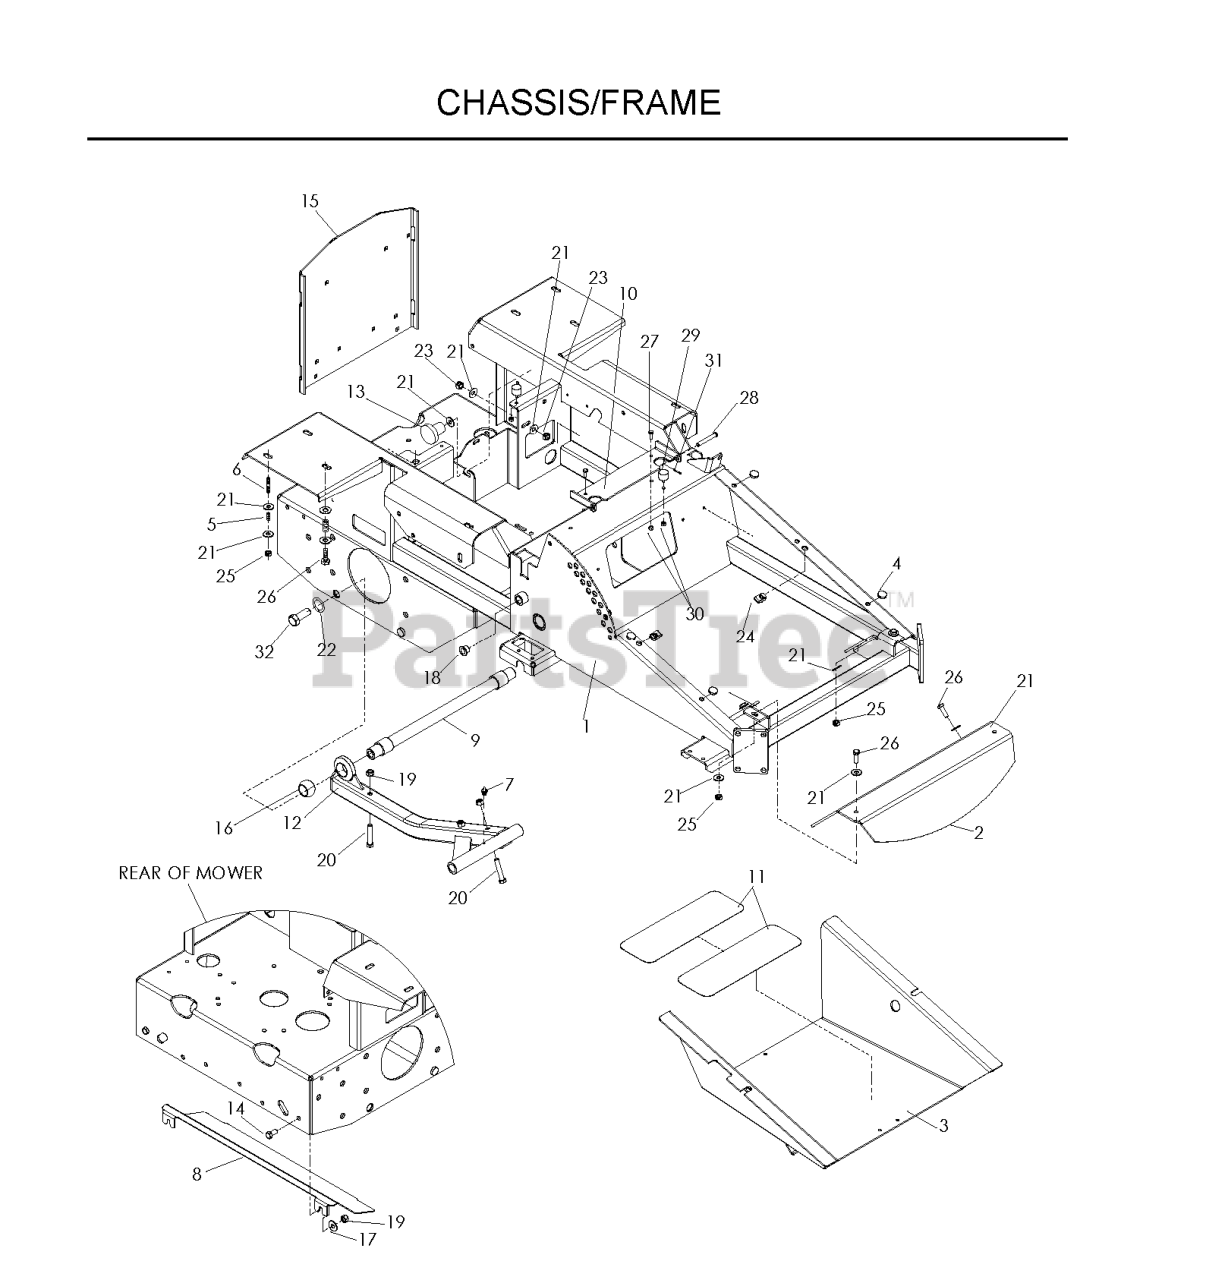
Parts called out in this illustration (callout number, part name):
1	CHASSIS W/DECALS
2	FOOTREST ORANGE
3	IZ FOOTPLATE W/DECAL
4	GROMMET, BUMPER
6	STUD, 5/16C
7	ZERK
8	REAR GUARD
9	STRUT MOUNT WELDMENT
10	SEAT BRKT W/DECAL
11	ANTI-SKID PAD
12	STRUT, LEFT
12	STRUT, RIGHT
14	SCREW 3/8C X 3/4 HEX CAP
15	ENGINE GUARD
17	WASHER 3/8 FLAT
19	NUT 3/8-16 NYLOC
20	HCS 3/8C X 2
21	WASHER 5/16 FLAT
22	LOCKWASHER 5/8
23	NUT 5/16C CENTERLOCK
24	U-CLIP 5/16-18 NUT RETAINER
25	NUT 5/16 NYLOC
26	HCS 5/16C X 1
27	HCS 1/4C X 3/4 HCS
28	CLEVIS PIN 3/8
29	STUD/PLATE MOUNT
30	NUT.1/4-20.HEX.NYLOC.ZD
31	RP_COTTER PIN 1/8 X 3/4
32	HCS 5/8C X 2 GR.5
